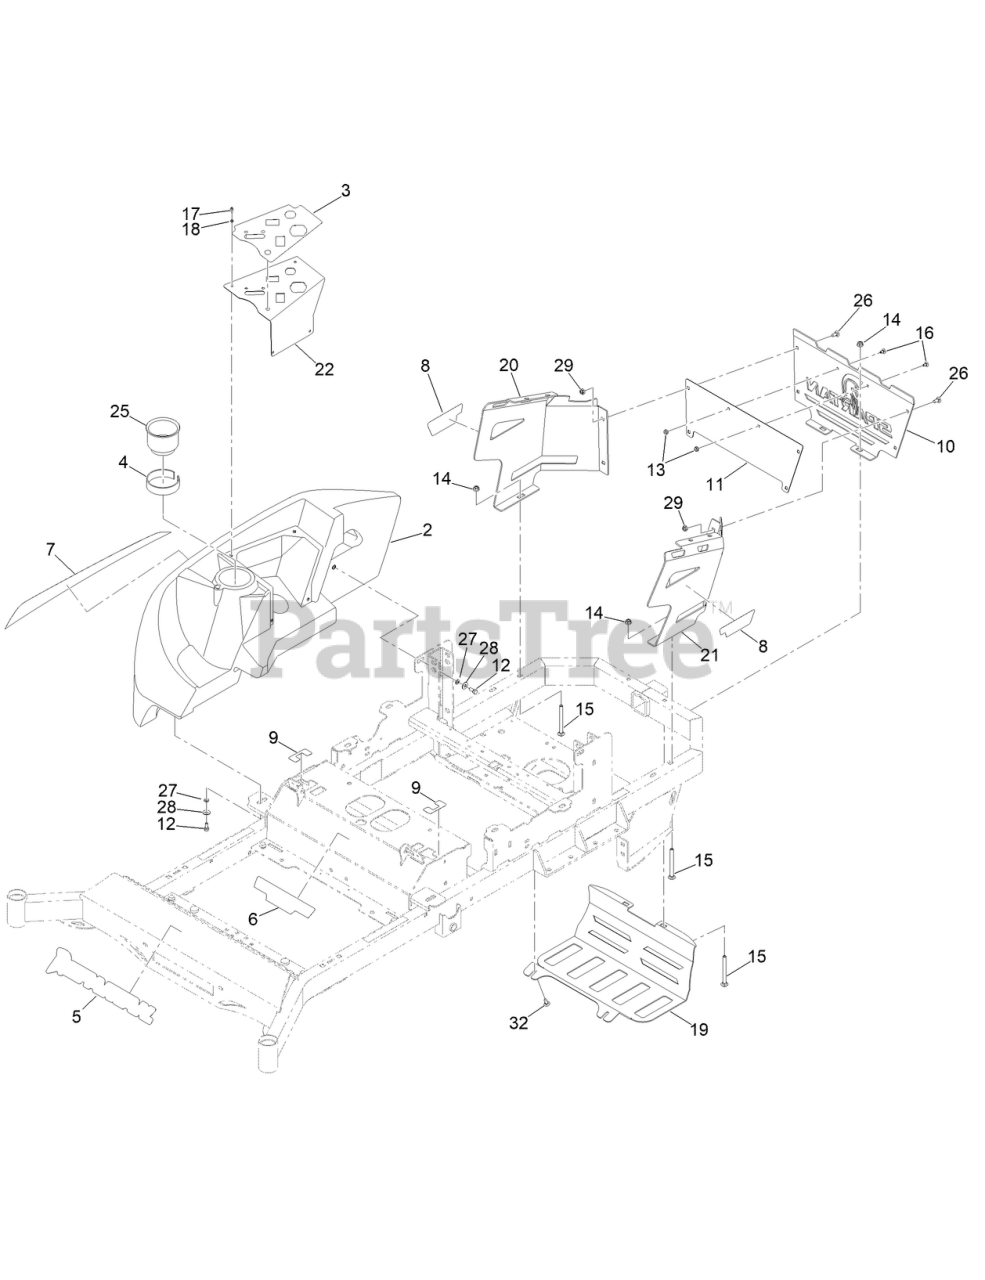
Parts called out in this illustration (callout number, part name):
2	CONSOLE W/ CUPHOLDER
3	DECAL-CONTROL PANEL
4	TAPE-FOAM
5	DECAL-SPARTAN, FRONT
6	DECAL- RT-PRO GT TRAC MODEL
7	DECAL-TANK
8	DECAL-MODEL
9	DECAL-MOTION CONTROL
10	PLATE - ENGINE COWLING
11	PLATE -BACKER PLATE
12	SCREW-HH
13	1/4-20 HEX FLANGE NUT W/SERR ZINC
15	3/8-16 X 4 CARRIAGE BOLT ZINC
16	1/4-20 X 1/2 CARRIAGE BOLT,YZ
17	10-24 X 1/2 SOCKET C/S 18-8 SS
18	#10 SPLIT LOCKWASHER 18-8 SS
19	MUFFLER GUARD [GRAY]
20	2021 RT/SRT ENGN COWLING RTPAINTED
21	2021 RT/SRT ENGN COWLING LT PAINTED
22	RT 45 KEY MNT
25	CUP HOLDER
26	BOLT-CARR
27	WASHER-LOCK
28	WASHER-FLAT
32	BOLT-HWH
